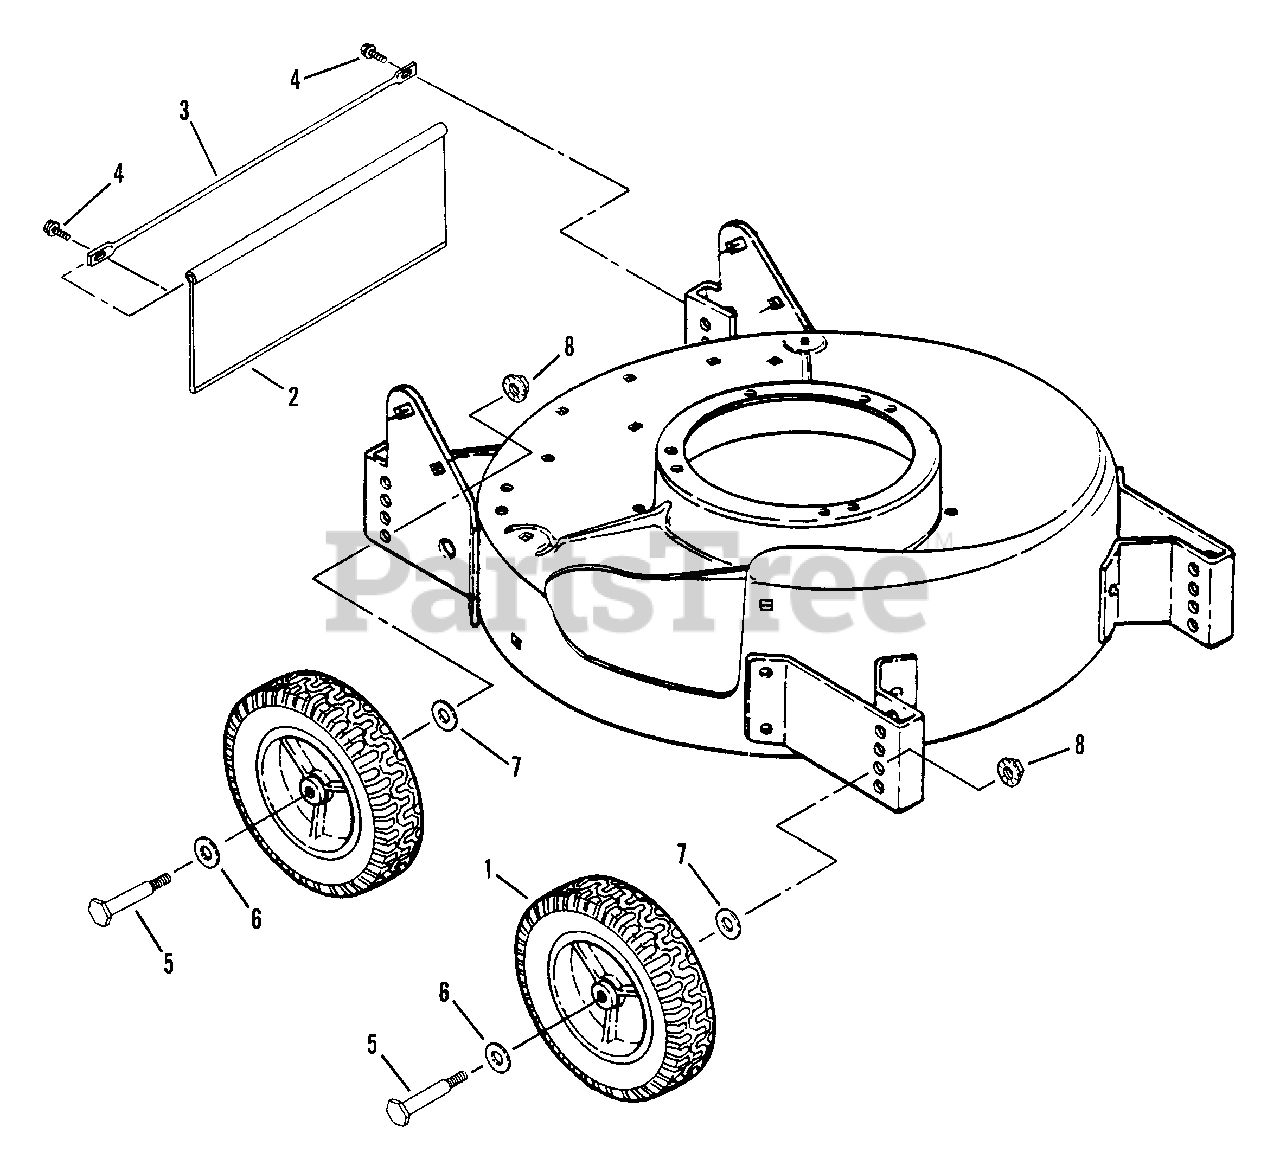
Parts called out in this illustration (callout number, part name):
1	WHEEL, Front & Rear 8 x 2.00
2	GUARD, Rear Foot
3	SUPPORT, Foot Guard
4	SCREW, #10-24 x 1/2" Hex Washer Self-Tap (Torx)
5	BOLT, 3/8-16 x 2-7/16" Shoulder
6	WASHER, 5/8 Belleville
7	WASHER, 9/16 x 1-1/16" O.D. Thrust
8	NUT, 3/8-16 Hex Flange Lock
